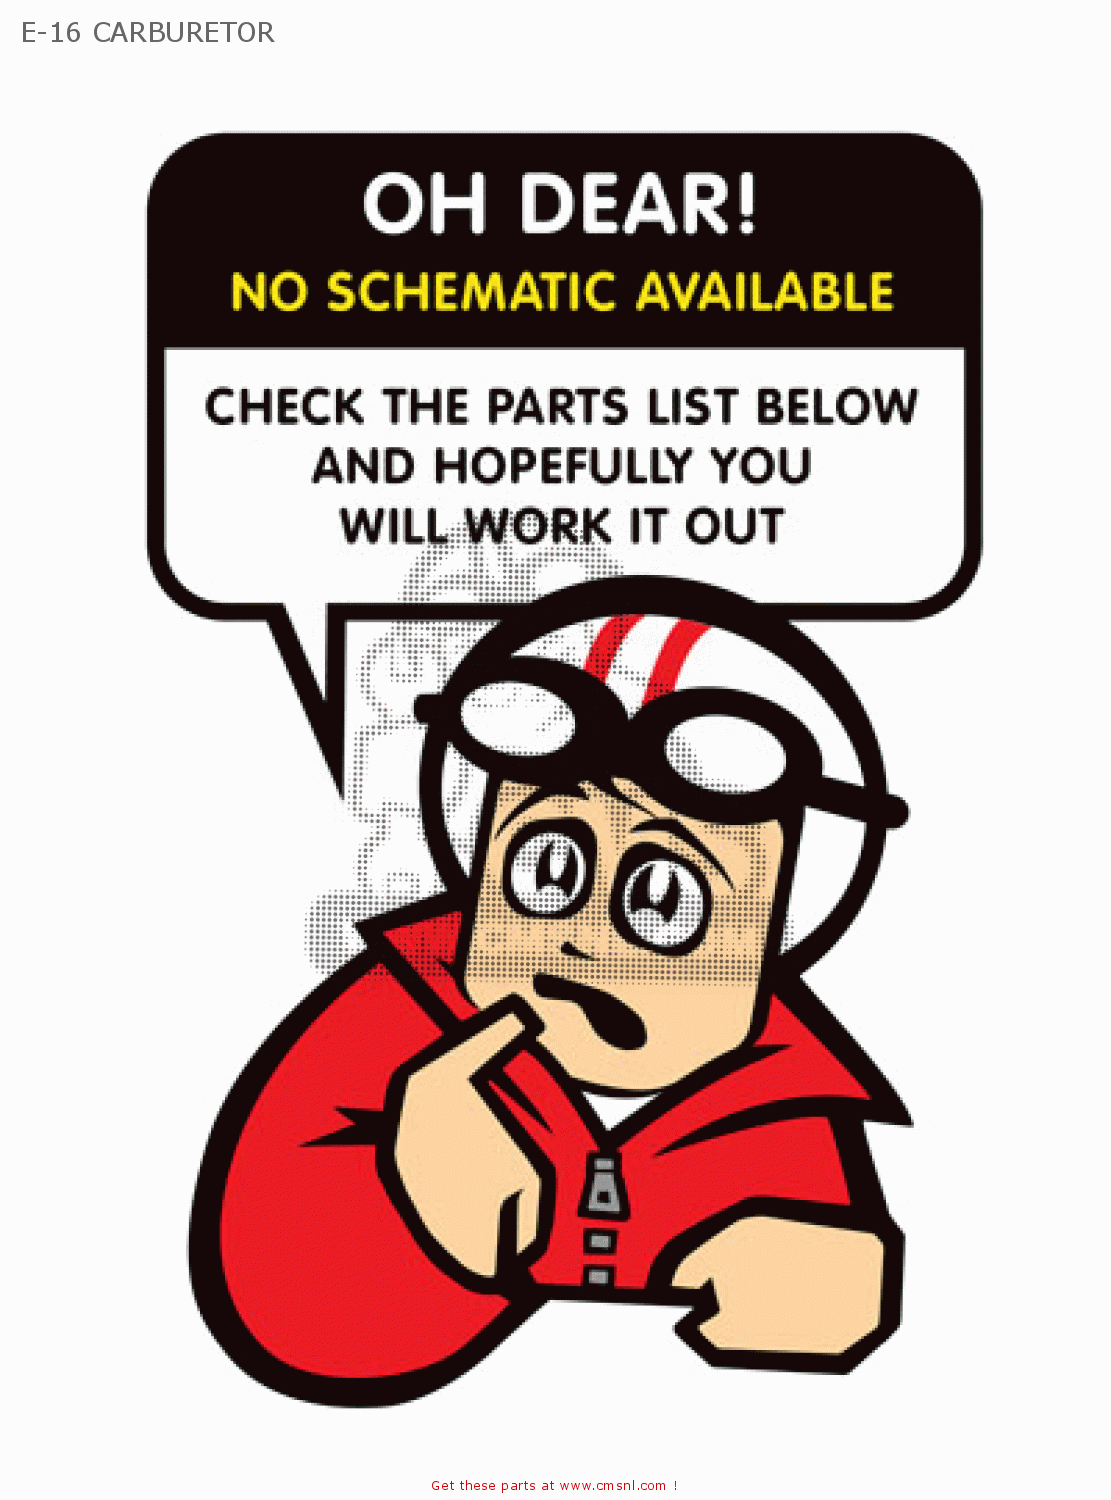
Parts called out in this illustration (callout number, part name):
1	LAMP-SIGNAL
2	SCREW-PAN HEAD,4X35
3	WASHER,PLAIN,4MM
4	LENS-SIGNAL LAMP,6.14
5	GASKET,TURN SIGNAL LA (NAS)
6	BULB 12V 32CP
7	BRACKET-SIGNAL LAMP
8	DAMPER,LAMP
9	DAMPER
10	COLLAR
11	NUT,10MM
12	WASHER-SPRING,10MM
13	WASHER-PLAIN
14	WIRE-LEAD,L=185
15	COLLAR
16	DAMPER
17	BOLT-UPSET
18	WASHER-PLAIN,6MM
19	WASHER-SPRING,6MM
20	NUT,6MM
21	LAMP-SIGNAL
22	LAMP-SIGNAL
23	BULB 12V 32CP
